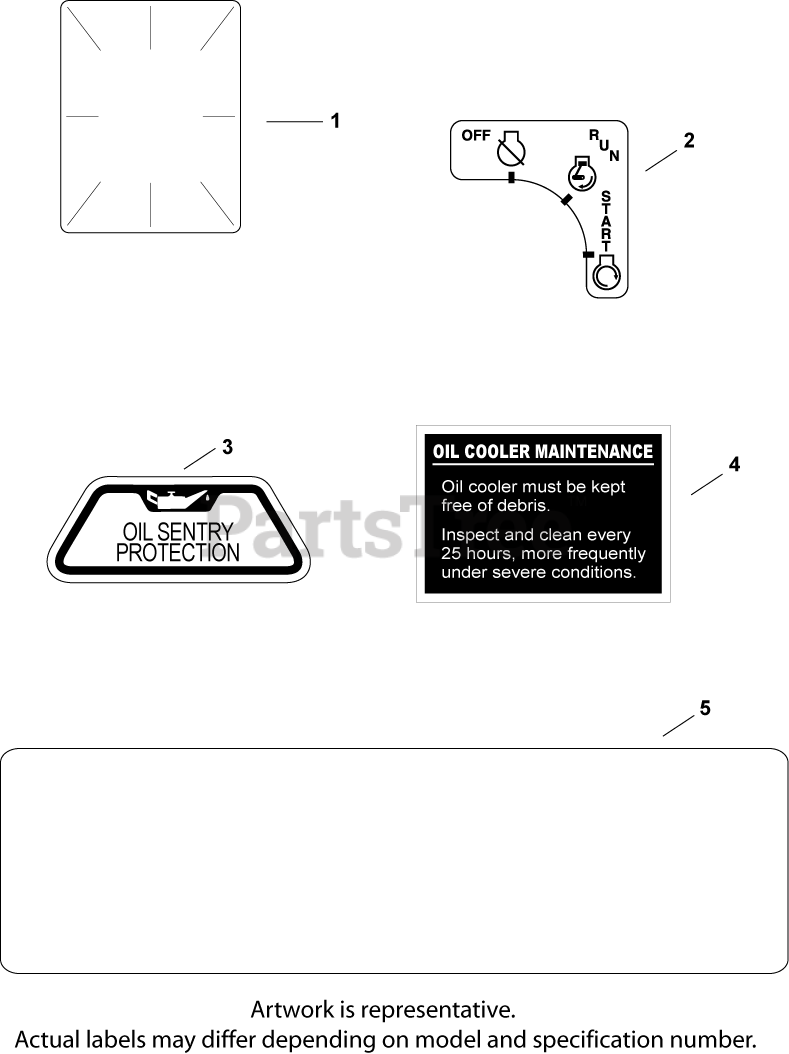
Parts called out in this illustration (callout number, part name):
1	DECAL, CLEAR LAMINATE USE 25 113 70-S
2	DECAL, KEY SWITCH
3	DECAL, OIL SENTRY - (#DSC)
4	DECAL, AIR CLEANER - (#DSC)
5	DECAL, 25 HP
